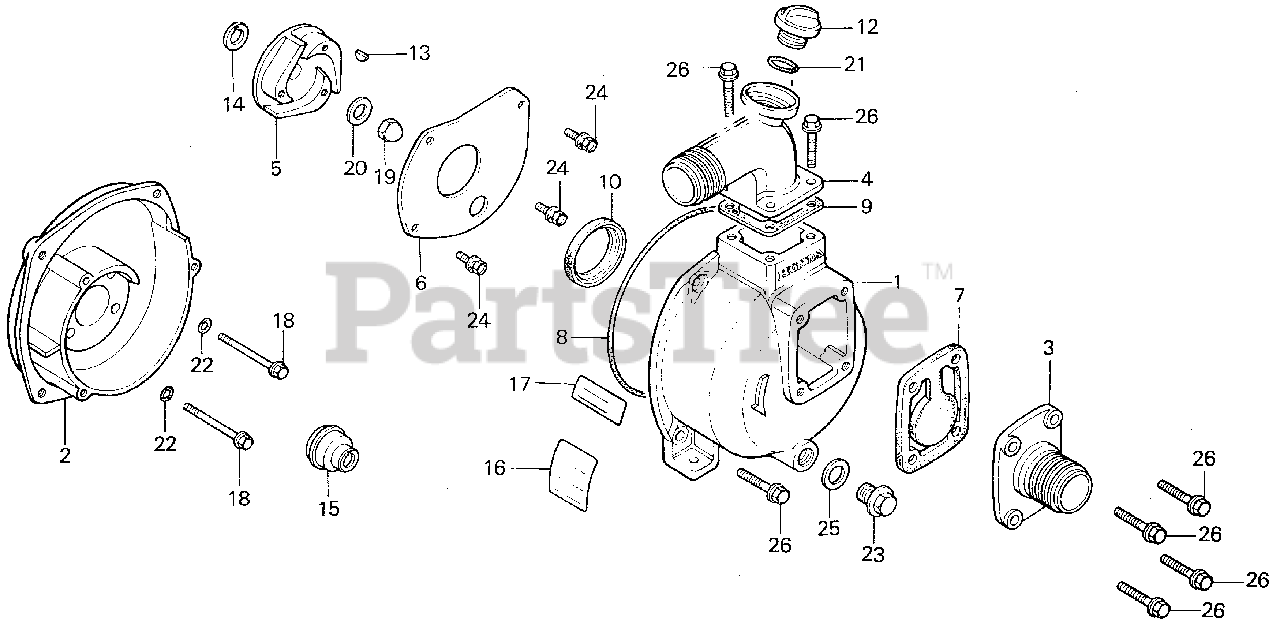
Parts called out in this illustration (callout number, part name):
2	COVER, CASE
3	MOUTH, IN.
4	MOUTH, OUTLET
6	DISK, FRICTION
7	VALVE, IN.
8	RING, CASING SEAL
9	GASKET, OUTLET
10	RING, CENTER SEAL
12	CAP, FILLER
13	KEY, IMPELLER
14	SHIM, ADJUSTER
15	SEAL ASSY., MECHANICAL WATER
16	PLATE, DESCRIPTION
17	PLATE, CAUTION
18	BOLT, PUMP SETTING
19	NUT, IMPELLER
20	WASHER (13MM)
21	O-RING, FILLER CAP
22	O-RING (7.5MM)
23	BOLT, DRAIN PLUG (20MM)
24	BOLT-WASHER (8X20)
25	WASHER, DRAIN PLUG (20MM)
26	BOLT, FLANGE (10X28)
